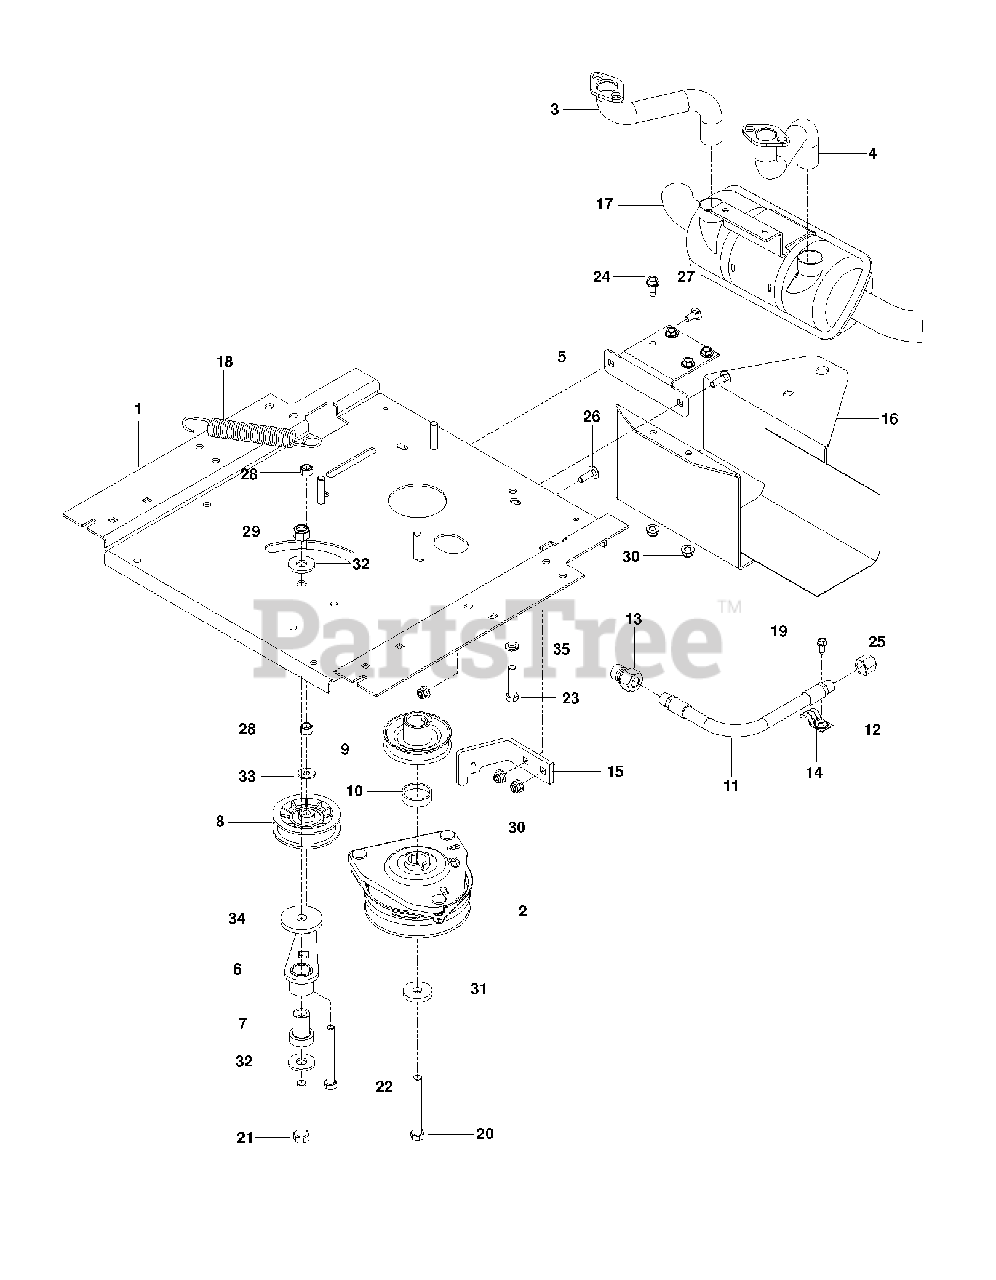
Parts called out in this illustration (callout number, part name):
5	BRACKET, MUFFLER, BLACK
6	IDLER ARM
7	IDLER SPINDLE
8	PULLEY, IDLER
9	PULLEY, ENGINE
10	SPACER, HUB PULLEY
12	DRAIN CAP
13	ADAPTER, OIL DRAIN
15	CLUTCH STOP OGR BLK
18	SPRING, DECK DRIVE
19	HCS 7/16-20 X 2.5 GR8
19	HEAT SHIELD
20	HCS 1/2C X 3 1/4
21	HCS 3/8-16X3 1/2 GR5
22	BOLT, HCS 3/8-16X1-3/4
23	BOLT 5/16-18 X 3/4
24	SCREW 1/4 X 5/8
25	RHSNB 5/16C X 1
26	BOLT 5/16C X 3/4" CARRIAGE
27	NUT 3/8-16 NYLOC
28	NUT 1/2-13 HEX NYLOC ZD
29	5/16-18 NYLOC FLANGE NUT
31	WASH USS FLAT 1/2
32	WASHER 5/16 FLAT
33	HEAVY WASHER
34	SLW 3/8 STD
